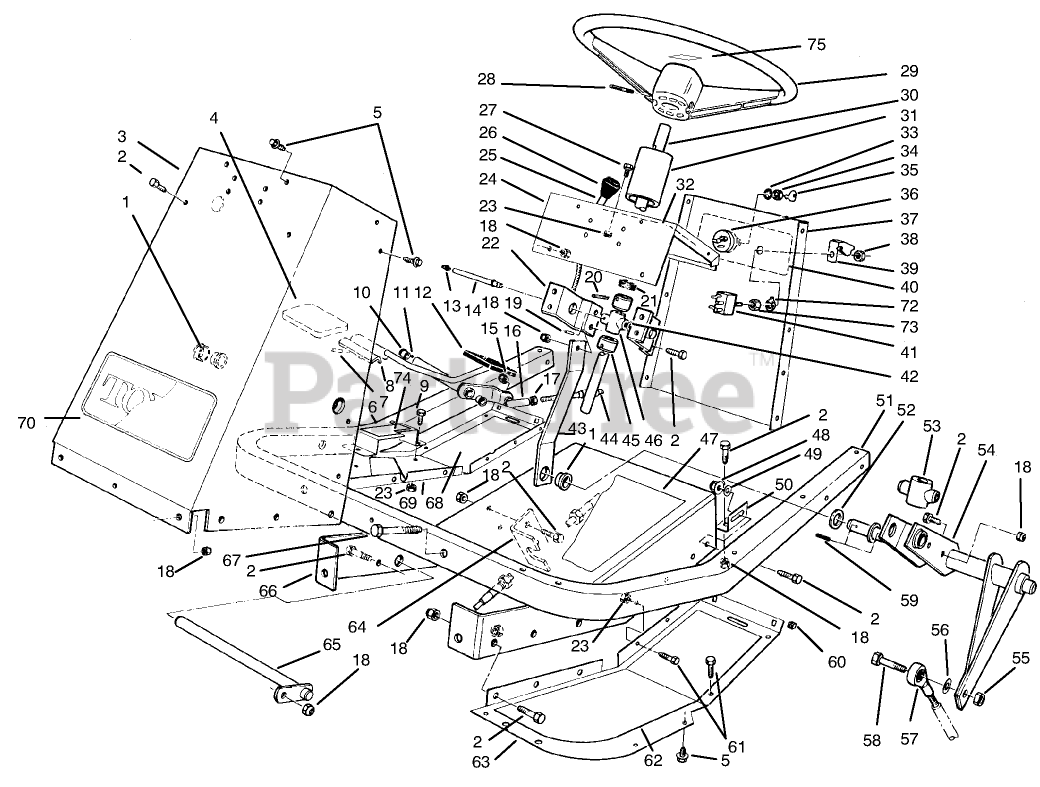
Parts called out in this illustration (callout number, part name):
1	BEARING-FLANGE
2	SCREW-HH
3	Tower-Front
4	FORWARD PEDAL PAD
5	SCREW-HHFTF
6	Footrest-Pedal
7	PIN-ROLL
8	ACCELERATOR PEDAL
9	SCREW-HH
10	BUSHING-FLANGE
11	Pedal-Traction (Incl. Ref. #10)
12	REVERSE PAD
13	FITTING-GREASE
14	TUBE ZERK
15	NUT-LOCK
16	JOINT-BALL
17	NUT-JAM
18	NUT-LOCK, NI
19	3/32 X 9/16 ROLL PIN
20	PIN-SPRING
21	COVER-DUST
22	BRG SUPT BRKT
23	NUT-LOCK, NI
24	Tower-Top
25	CONTROL-CHOKE,THROTTLE
27	SCREW-HH
28	PIN-ROLL
29	STEERING WHEEL ASM
30	Shaft-Steering
31	STRG. SHAFT COVER
32	THROTTLE DECAL
33	WASHER-TOOTH, INTERNAL
34	NUT-HH
35	KEY-IGNITION
36	Switch-Ignition (Incl. Ref. #33-35)
37	Panel-Tower Rear
39	COVER-PTO SWITCH
40	SWITCH DECAL
41	Switch-Clutch & Brake (Incl. Ref. #38, 72 & 73) 1
42	WASHER-BELLEVILLE
43	Link-Steering
44	TRACT CONT.CABLE
45	STRG SHAFT COLLAR
46	BRG STEERING SHAFT
47	TUNNEL DECAL
48	NUT-HF
49	WASHER-PLAIN
50	TUNNEL BRKT
51	Frame-Footrest
52	WASHER-THRUST
53	STEER.SHAFT FOLLOWER
54	Follower Lever
55	NUT-LOCK, NI
56	WASHER-FLAT
57	BALL JOINT LH
58	SCREW-HH
59	PIN-ROLL
60	NUT-RETAINED
61	SCREW-HH
62	FOOT REST PAD LH
63	Footrest-L.H.
64	TRACT CABLE BRKT
65	PEDAL.SHAFT WA
66	Tunnel
67	SCREW-HH
68	FOOT REST PAD RH
69	Footrest-R.H.
70	DECAL
72	TAB-WASHER
73	NUT-HEX, SPECIAL
74	FOOTREST PAD
75	DECAL
